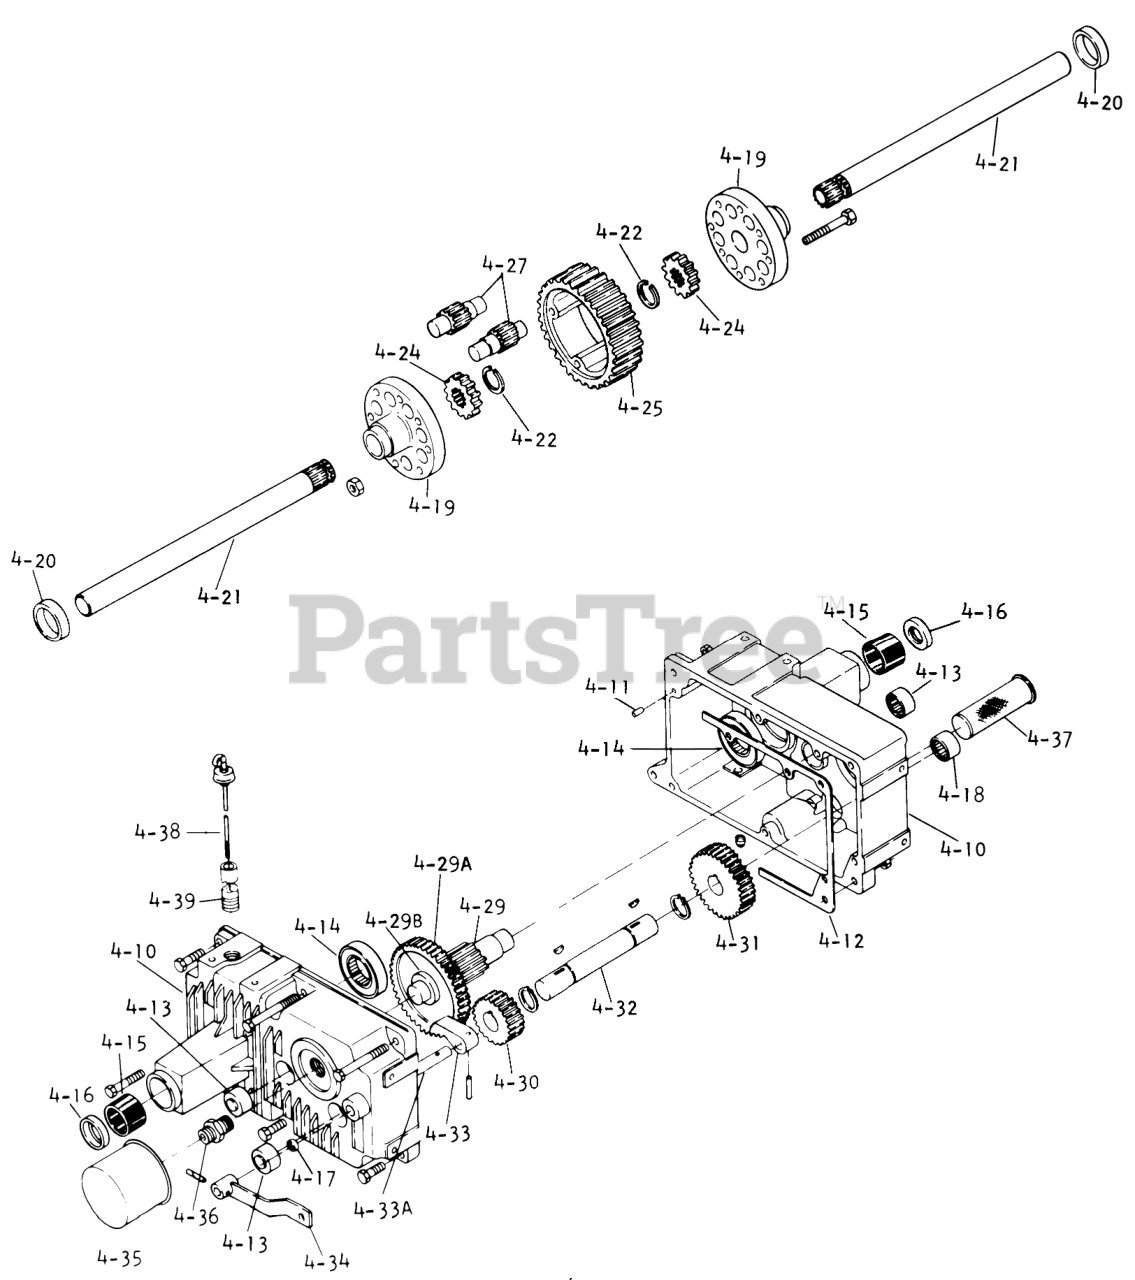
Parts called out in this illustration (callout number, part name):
4-10	RH TRANSMISSION CASE
4-11	PIN-DOWEL
4-12	GASKET
4-13	BEARING-NEEDLE
4-14	NEEDLE BEARING
4-15	Bearing-Axle
4-16	SEAL-OIL
4-17	SEAL BRAKE SHAFT
4-18	Needle Bearing
4-19	DIFFERENTIAL END CAP
4-20	RACE BEARING
4-21	REAR AXLE
4-22	SNAP RING
4-24	GEAR-AXLE DIFFERENTIAL
4-25	GEAR-DIFFERENTIAL RING, 43T
4-27	GEAR-PINION, 11T
4-29A	GEAR 46T
4-29B	WASHER-THRUST
4-30	20T GEAR
4-31	Gear 44T
4-32	SHAFT GEAR
4-33	Parking Pawl
4-33A	Parking Shaft
4-34	LEVER BRAKE ASSY
4-35	Filter
4-36	FITTING
4-37	Strainer
4-38	Dipstick
4-39	Nipple
